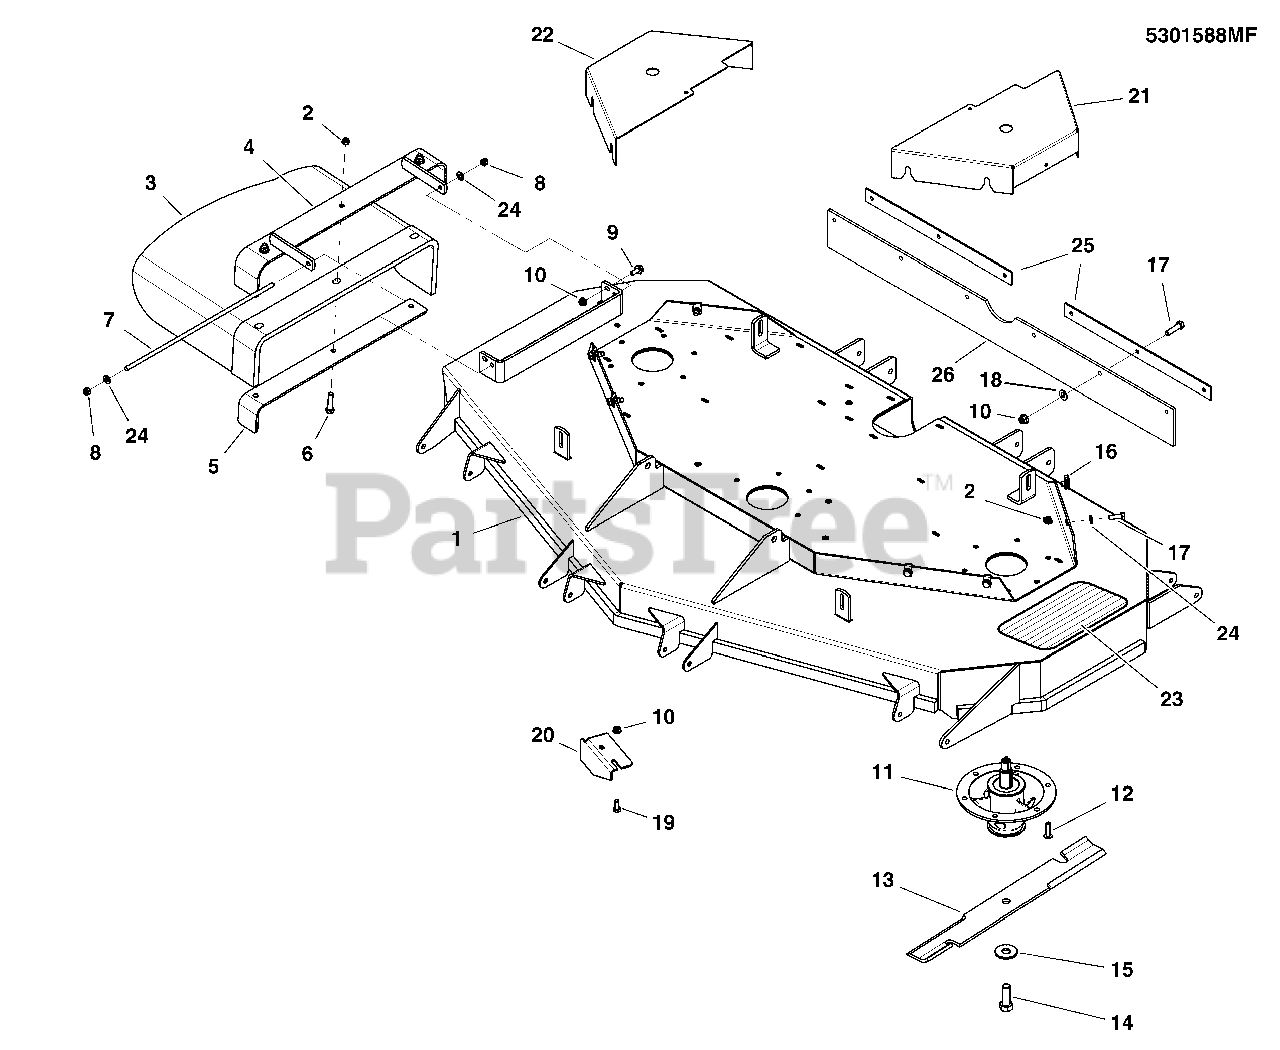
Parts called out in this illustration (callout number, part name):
1	DECK SHELL W/ DECALS, 61, S800X
2	NUT, 3/8-16 HEX NYLOCK FLANGE
3	CHUTE, DISCHARGE, BEND RUBBER (SV)
4	WELD, FRAME, CHUTE, 61 - BLK
5	SUPPORT, DISCHARGE CHUTE, 61/72 - BLK
6	BOLT, 3/8-16 X 1-1/2 GD5 YZ
7	ROD MOUNT, CHUTE 61"
8	NUT, 5/16-24 HEX NYLON LOCK
9	BOLT, 5/16-18 X 3/4"
10	NUT, 5/16-18 HEX NYLOCK FLANGE
11	SPINDLE ASSM, CAST IRON 8.0-6 BOLT
12	BOLT, 3/8-16 X 1", FLANGE
13	BLADE, 21" (SET OF 3)
14	BOLT, 5/8-11 X 1-3/4 GD8
15	WASHER, 5/8 USS
16	BODY CLIP, 5/16-18-7GA MATERIAL
17	BOLT, 5/16-18 X 1 GD5 YZ
18	NUT, Push On, 5/16
19	BOLT, 5/16-18 X 3/4, CARRIAGE
20	PLATE, DEFLECTOR - BLK
21	GUARD, 61, LH - OUTFRONT - RED
22	GUARD, 61, RH - OUTFRONT - RED
23	SAFETY WALK, 4.00 X 7.50
24	WASHER, 5/16 SAE
25	PLATE, SUPPORT, S800X - RED
26	FLAP, STRIPER, 61 DECK
